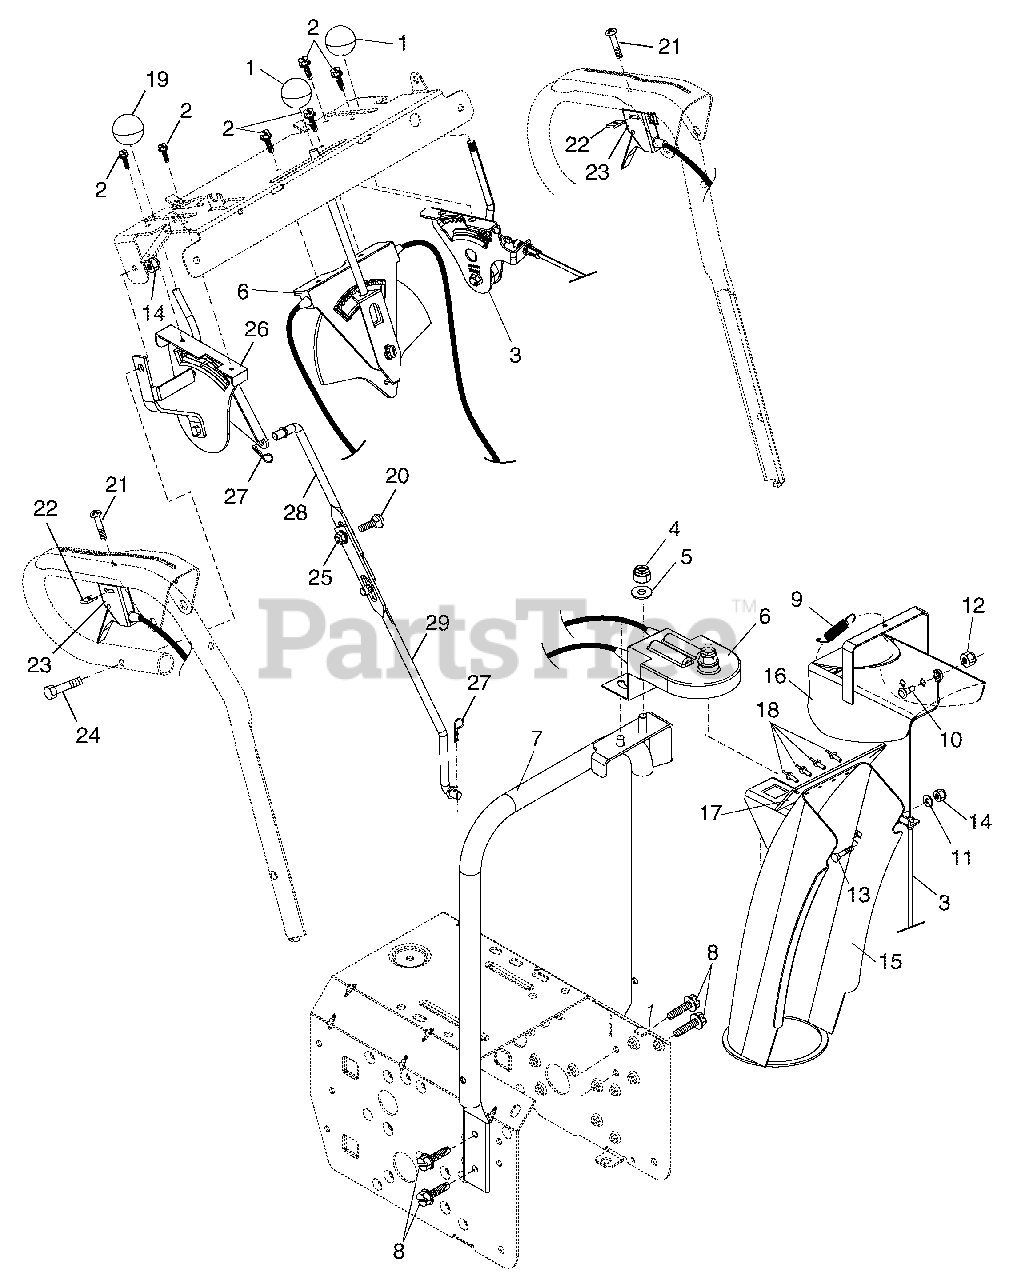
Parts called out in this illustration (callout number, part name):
1	Knob, Lever
2	Screw #10-24 x 5/8
3	Control Assembly, Deflector
4	Nut, Lock 3/8-16
5	Washer, Flat 3/8
6	Control Assembly, Chute Rotater
7	Support, Pivot
8	Screw, Hex Head 5/16-18 x 3/4
9	Spring, Deflector
10	Bolt, Shoulder
11	Washer, Flat
12	Nut, Lock 1/4-20
13	Bolt, Carriage 5/16-18
14	Nut, Lock 5/16-18
15	Chute Assembly
16	Deflector Assembly
17	Seal, Deflector
18	Rivet, Blind
19	Knob, Speed Control Lever
20	Bolt, Carriage 5/16-18 x 3/4
21	Screw #10-24 x 1-1/2
22	Nut, Weld #10-24
23	Control Assembly, Power Steering
24	Screw, Hex Head 5/16-18 x 1-3/4
25	Nut, Lock 5/16-18
26	Lever Assembly, Speed Control
27	Retainer, Hairpin
28	Rod, Upper, Speed Control
29	Rod, Lower, Speed Control
